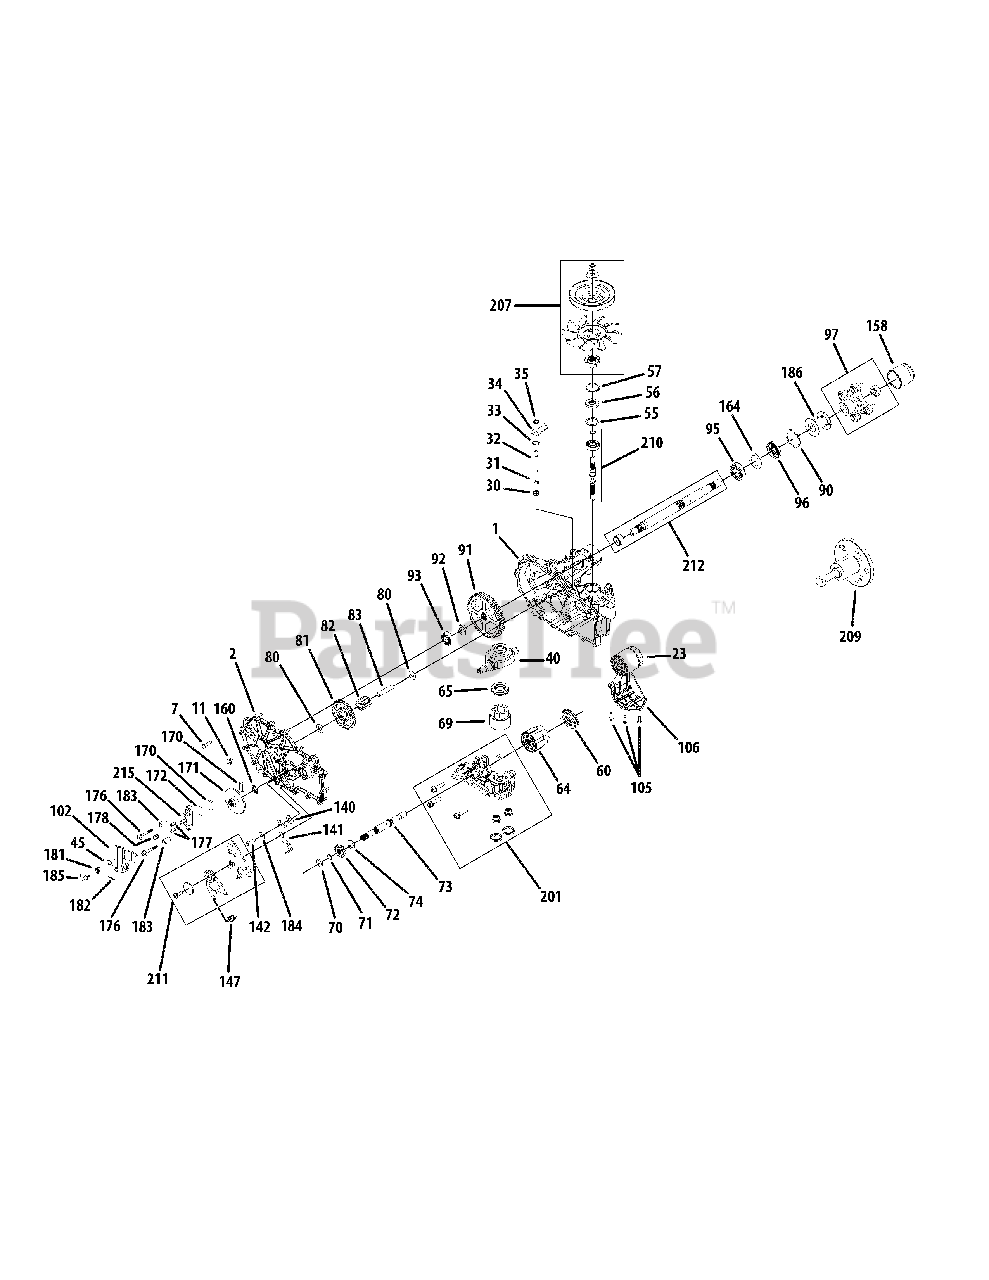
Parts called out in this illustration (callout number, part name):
1	Kit, Housing, Main, LH
2	Kit, Cover Side LH Control
7	Screw, Hex Washer
23	Filter, Spin-On 2.6 x 3.0
30	Seal, Lip, .375 x .75 x .25
31	Ring, Retaining .375 External
32	Rod, Bypass
33	Ring Retaining .750 Internal
34	Arm, Bypass
35	Ring, Ret .375 External
40	Trunnion, Swashplate
45	Washer, .34 x .88 x .06
55	Washer, 1.23 x 1.57 x .04
56	Seal, Lip 17 x 40 x 7
57	Ring Retaining Internal
60	Bearing, Thrust 35 x 62 x 18
64	Kit, 16cc Cylinder Block Assembly
65	Thrust Bearing, 30 x 52 x 13
69	Kit, Block, 7 Piston
70	Washer, .63 x 1.00 x .05
71	Ring, Reatining, Motor Shaft
72	Gear, 16T
73	Shaft, Motor
74	Washer, .71 x 1.16 x .04
81	Gear, 43T
82	Gear, 11T
83	Pin, Jackshaft
90	Ring, Retaining 2.25 Internal
91	Gear, 54T
92	Spacer, .750 x 1.00 x .257
93	Bearing, Ball 3/4 x 40mm x 12mm
95	Bearing, Ball 25.4 x 52 x 15
96	Seal, Lip, 1.0 x 2.06 x .38
97	Kit, Hub 4-Bolt
102	Arm, Brake
105	Screw, Hex Washer 1/4-20 x .75
106	Guard, Filter, LH
140	Spacer, .320 x 1.005 x .150
141	Arm, Neutral Right
142	Socket Cap Screw, 5/16-24 x 7/8
147	Spring, Extension
158	Cap, Axle
160	Seal, Lip .625 x 1.00 x .250
164	Spacer, 1.355 x 2.035 x .021
170	Puck, Brake
171	Rotor, Brake
172	Puck, Plate
176	Screw, .250-20 x 2.0 HFS Patch
177	Pin, Brake Actuating
178	Compression Spring
181	Nut, Castle 5/16-24
182	Pin, Cotter 3/32 x 3/4
184	Washer, .34 x .88 x .06
185	Spring, Brake Arm Bias
186	Tube, Axle 2.03
200	Kit. Seal, ZT-2800
201	Kit, Center Section RH
207	Kit, Fan Pulley
207	Fan Only
207	Pulley Hub
209	Kit, Hub Puller
210	Kit, Input Shaft
211	Kit, RTN Bidirectional
212	Kit, Shaft Axle
215	Kit, Brake Yoke
